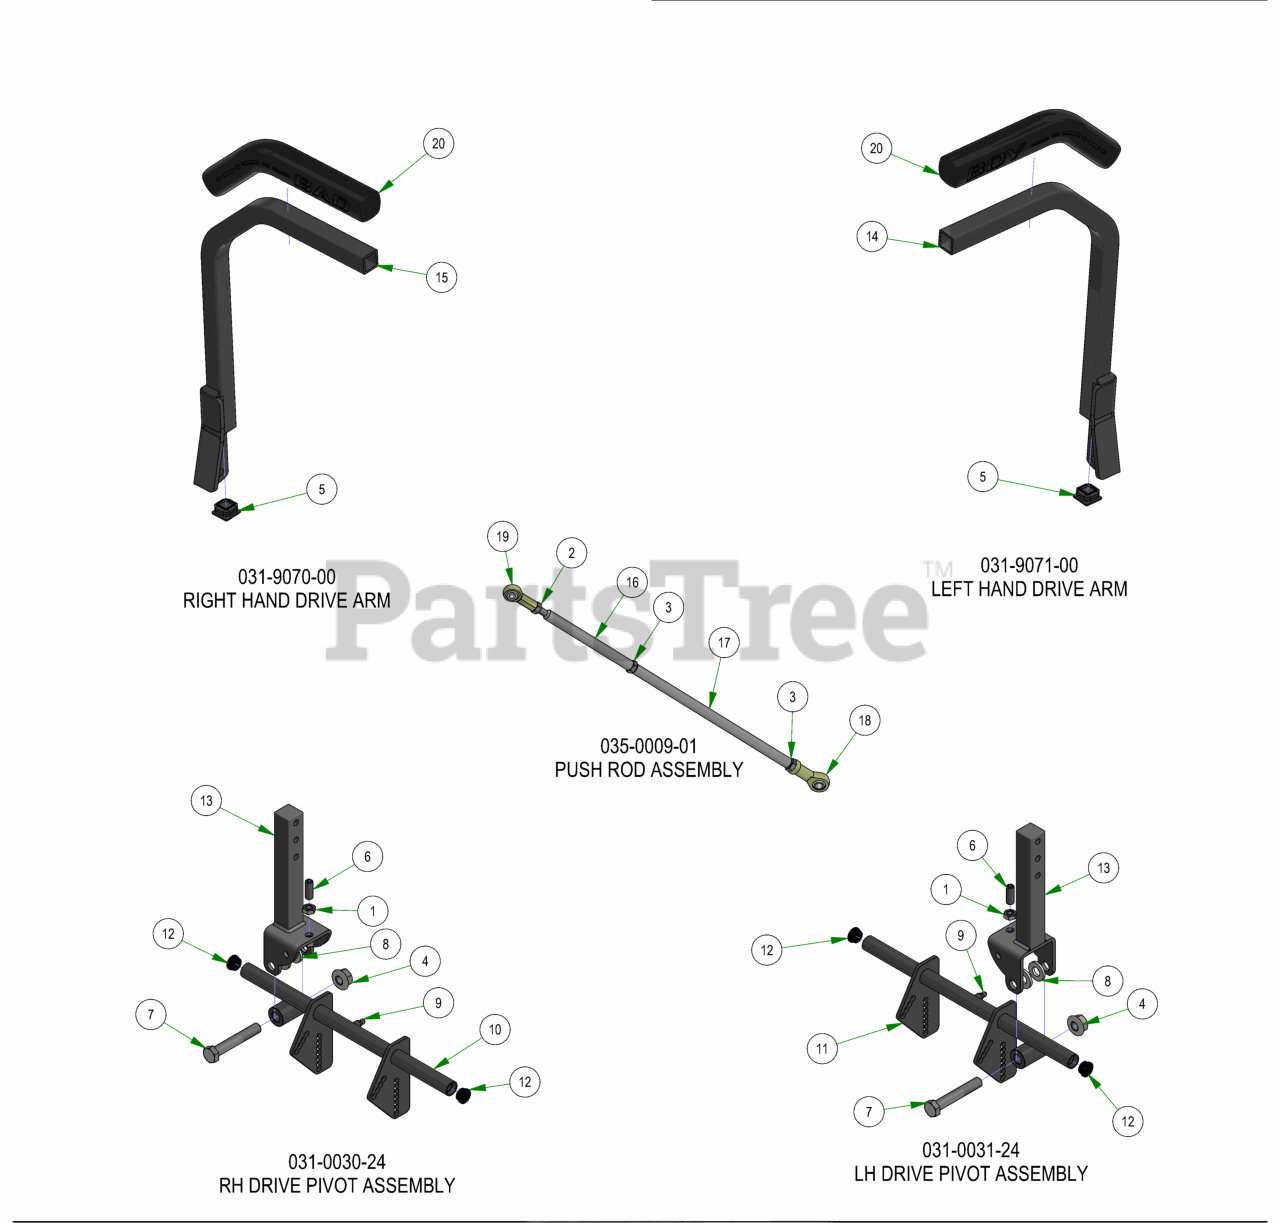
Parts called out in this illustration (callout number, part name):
1	3/8-16 Half Jam Nut
2	5/16 LH Nut
3	3/8-24 HEX NUT ZINC YELLOW
4	1/2-13 NYLON INSERT FLANGE LOCKNUT ZINC
5	9565K52_Polyethylene Square Plug
6	3/8-16 X 1 SOCKET SET SCREW (CUP POINT) PLAIN
7	1/2-13 X 3 HEX CAP SCREW (GR.5) ZINC
8	.505 ID X 1.000 OD X .125 THICK FLAT WASHER NYLON
9	1/4 DRIVE-TYPE STRAIGHT GREASE FITTING ZINC YELLOW)
10	2019 Drive Arm Actuator right - Weldment
11	2019 Drive Arm Actuator left - Weldment
12	2019 Drive Arm Bushing
13	R Series Square Drive Arm Pivot
14	R Series Square Drive Arm LH Weldment
15	R Series Square Drive Arm RH Weldment
16	2019 Renegade Push Rod Adjuster
17	2024 Rebel Push Rod
18	Spherical Rod End - Outlaw
19	Spherical Rod End - Outlaw
20	R-Series Square Drive Grip
